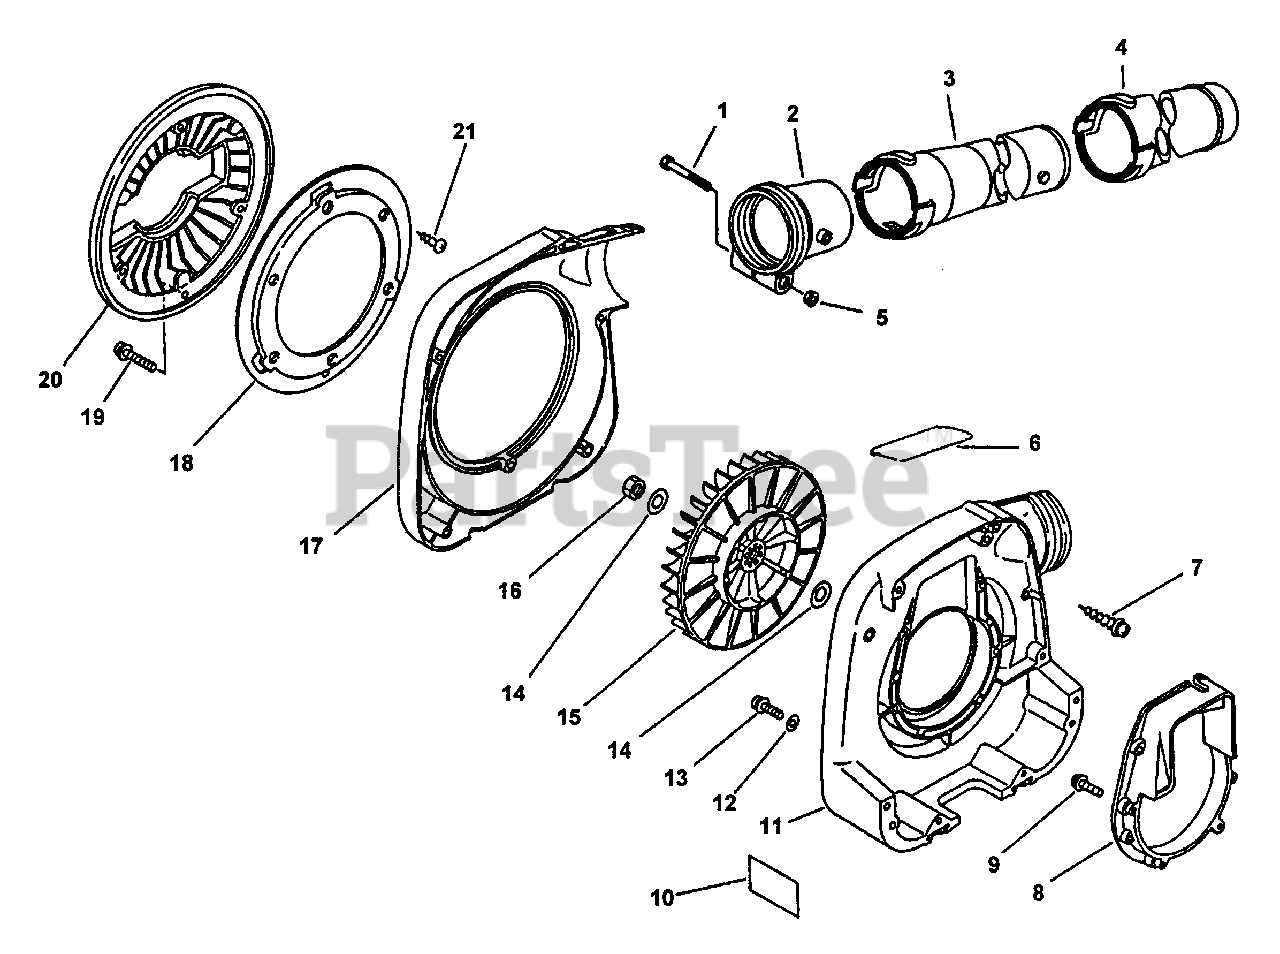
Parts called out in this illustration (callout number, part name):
1	SCREW - 5X60
2	ADAPTER, TUBE
3	TUBE, BLOWER - STRAIGHT
4	TUBE, BLOWER - NOZZLE
5	NUT - 5 -- FLANGE
6	LABEL - NOISE
7	SCREW - 5X30
8	BRACKET, ENGINE
9	SCREW - 4X18
10	LABEL - CAUTION
11	COVER, FAN - RIGHT
13	SCREW - 4X22
14	WASHER - 8
15	FAN
17	COVER, FAN - LEFT
18	BASE, GRID
19	SCREW - 5X16
20	GUARD, DEBRIS
21	SCREW - 4X10
